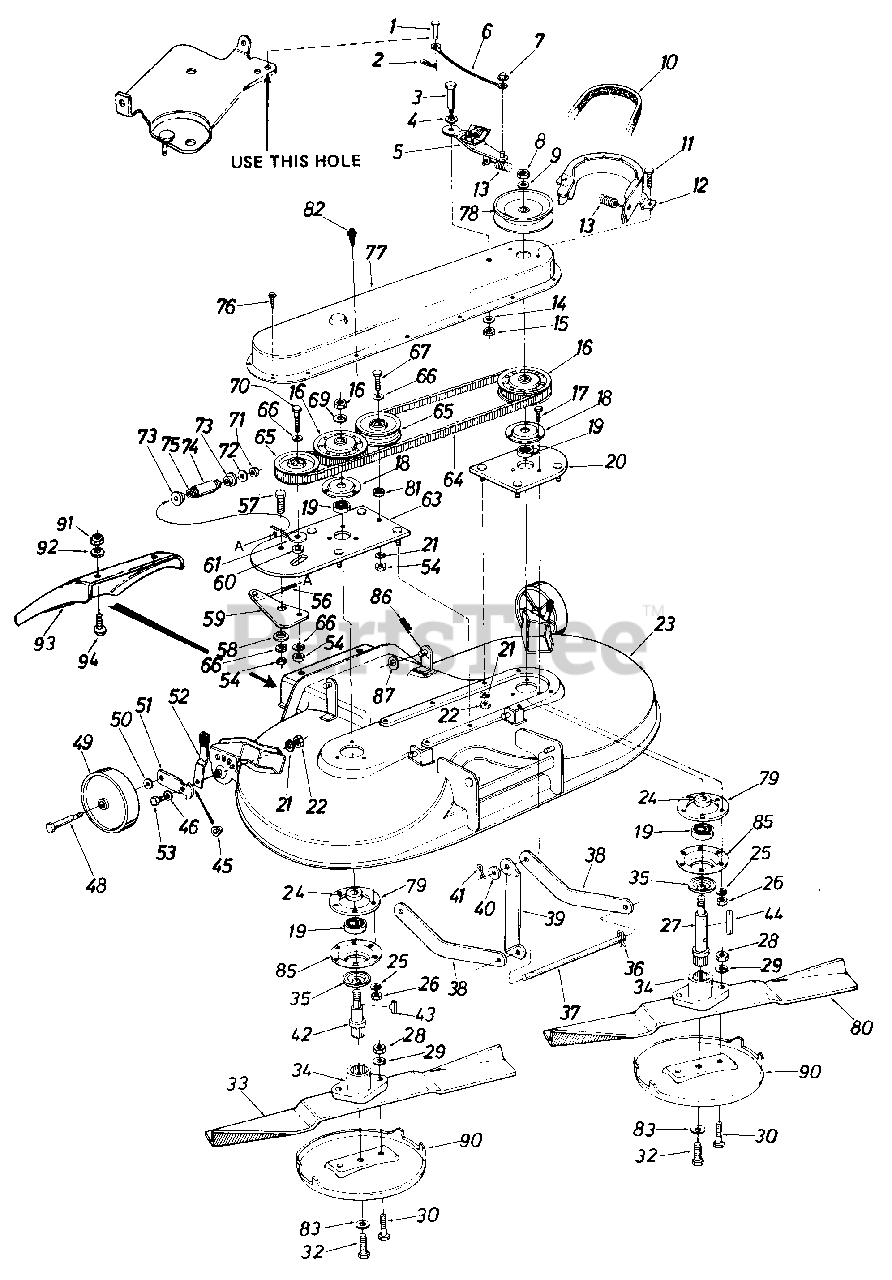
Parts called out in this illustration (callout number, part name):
1	Clevis Pin 1/4" Dia. x 1/2" Lg.
2	Hairpin Cotter 1/4" Dia.
3	Shld. Bolt .437" Dia. x .180" Lg. (5/16-18)
4	Wave Washer 7/16" Scr.
5	Spindle Brake Arm Ass'y.
6	Brake Cable Ass'y.
7	Push Cap 1/4" Stud.
8	Hex Jam Nut 5/8-18 Thd.
9	Bell.-Wash. 5/8" I.D. x 1.25" OD)
10	"V" Belt
11	Hex Wash. Hd. Self Tap Scr. 1/4-20 x .50" Lg.
12	Belt Guard
13	Extension Spring
14	Bell.-Wash. .340" I.D.
15	Hex Cent. L-Nut 5/16-18 Thd.
16	Sprocket Pulley Ass'y.
17	Hex Bolt 5/16-24 x 1.00" Lg. (Grade 5)
18	Bearing Housing
19	Ball Bearing .787" I.D. x 1.85" O.D.
20	Spindle Plate Ass'y.
21	L.-Wash. 3/8" I.D.*
22	Hex Jam Nut 3/8-24 Thd.
23	44" R.C. Deck Ass'y.
24	Spacer
25	L.-Wash. 5/16" I.D.*
26	Hex Nut 5/16-24 Thd.*
27	Blade Spindle - L.H.
28	Hex Nut 5/16-24 Thd.*
29	L.-Wash. 5/16" I.D.*
30	Hex Bolt 5/16-24 x 1.00" Lg.
32	Hex Bolt Cent. L.-3/8 x 24 x 88" Lg.
33	22.5" Blade-L.H. Rotation
34	Blade Adapter
35	Bearing Shield
36	Hairpin Cotter
37	Deck Connecting Rod
41	Cotter Pin 3/32" Dia. x 1.00" Lg.*
42	Blade Spindle - R.H.
43	Sq. Key 3/16" x 75" Lg.*
44	Sq. Key 3/16" x 1.50" Lg.*
45	Shoulder Spacer
46	Bell.-Wash. .400" I.D.
48	Shld. Bolt 3/8-16 x 1.41" Lg.
49	Wheel Ass'y. Comp. 6" x 1.38
50	Bell-Wash. 3/8" I.D.
51	Wheel Pivot Bar
52	Spring Lever Ass'y. w/knob
53	Hex Bolt 3/8-24 x 1.25" Lg. Grade 5
54	Hex Cent. L-Nut 3/8-24 Thd.
56	Adjustment Link 5/16-18 x 4-9116" Lg.
57	Hex Bolt 3/8-24 x 1.00"
58	Shld. Spacer.625" I.D.
59	Belt Idler Brkt.
60	Spacer.380" I.D. x .625" O.D. x .265
61	Fl.-Wash. .38" I.D. x 1.37" O.D. x .125
63	Spindle & Idler Mount Plate Ass'y.
64	HTD Twin Power Belt
65	Fl.-Idler Pulley 3.50" O.D.
66	Bell.-Wash. .38" I.D.
67	Hex Bolt 3/8-24 x 1.75" Lg. (Grade 5)
69	Bell.-Wash. 518" I.D.
70	Hex Bolt 3/8-24 x 2.00" Lg.
71	Hex Insert L.-Nut5/16-18 Thd.
72	Fl.-Wash. 344" I.D. x 1.125" O.D. x .125
73	Shld. Spacer.625" I.D.
74	Spacer-Adj. Bolt
75	Compression Spring
76	Hex Wash. Hd. Self Tap Scr. 1/4-20 x .50" Lg.
77	Belt Cover
78	Deck Drive Pulley
79	Deck Reinforcement Plate
80	22.5" Blade-R.H. Rotation
81	Fl.-Wash. .38" I.D. x 1.00" C) . D.
82	Hex Wash. Hd. Self Tap-Scr. 1/4-20 x .75" Lg.
83	L.-Wash. 3/8" I.D. Heavy Duty
86	Hairpin Cotter
87	Fl.-Wash. 1/2" I.D.
90	Anti Scalp Plate
91	Hex Nut 1/4-20 Thd.*
92	L.-Wash. 1/4" I.D.*
93	Chute Deflector
94	Truss Mach. Scr. 1/4-20 x .50" Lg.
